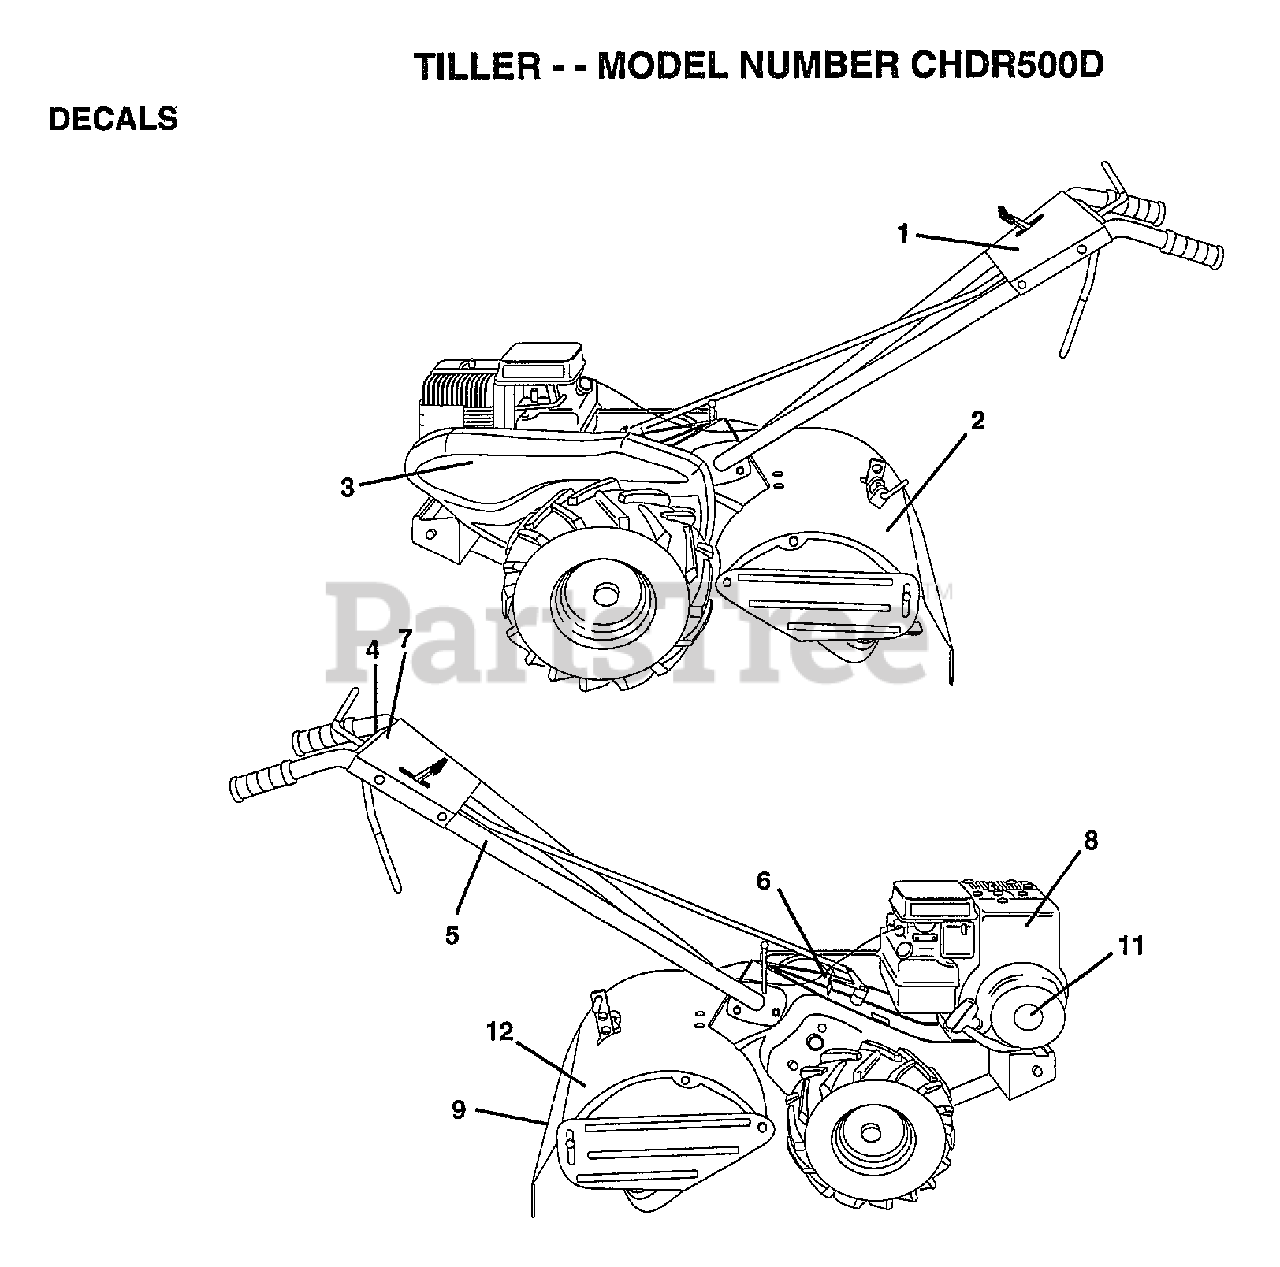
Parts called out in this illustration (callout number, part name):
1	"DECAL PANEL,CTRL"
2	"DECAL SHIELD,TINE"
3	DECAL.LOGO
5	DECAL TI
6	DECAL CRT
7	DECAL REVERSE
12	DECAL.CAUTION
